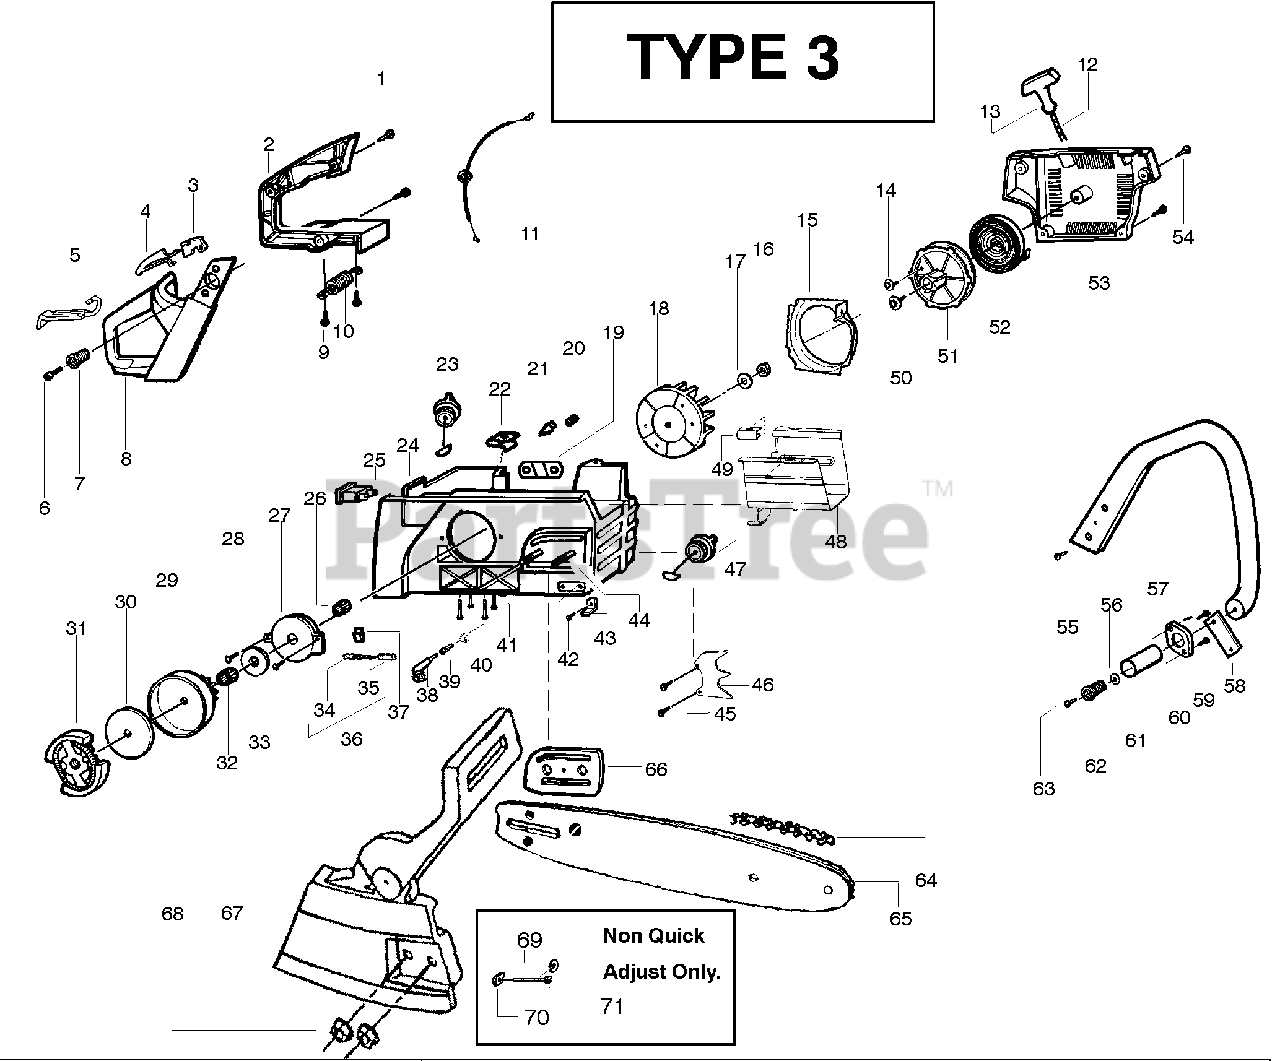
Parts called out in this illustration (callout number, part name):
2	Cover-Handle
3	Trigger-Throttle
4	Lockout-Throttle
7	Spring-Isolator
8	Handle-Rear
10	Spring-Isolator
11	Assy-Throttle Cable
13	Handle-Starter
15	Plate-Baffle Fan
17	Washer-Flywheel
18	Assy-Flywheel
19	Plate-Support (Bar Stud)
23	Assy-Fuel Cap
26	Worm-Oil Pump
27	Hsg.-Oil Pump
29	Kit-Clutch Drum
30	Washer-Clutch
32	Bearing-Clutch
33	Washer-Thrust
34	Assy-Plunger/Gear
35	Barrel-Oil Pump
36	Assy-Oil Pump
37	Seal-Oil
38	Pickup-Oil
39	Filter-Oil
40	Plug-Oil Filter
43	Chain Catcher
45	Screw
46	Kit-Spike Assy
47	Assy-Oil Cap
51	Kit-Starter Pulley
52	Spring-Recoil
53	Housing-Fan
57	Handle-Front
58	Front Strap-AV
60	Plate-Isolator
61	Spring Sleeve-AV
62	Spring-Isolator
65	Bar 16" Standard
65	Bar 20" Quick Adjust
65	Bar 20" Pro Lam Quick Adj.
67	Assy-ChainBrake (w/Standard Bar)
67	Assy-ChainBrake (w/Quick Adjust Bar)
68	Nut-Bar Mounting
70	Pin-Bar Adjust
71	Kit-Bar Adjust
